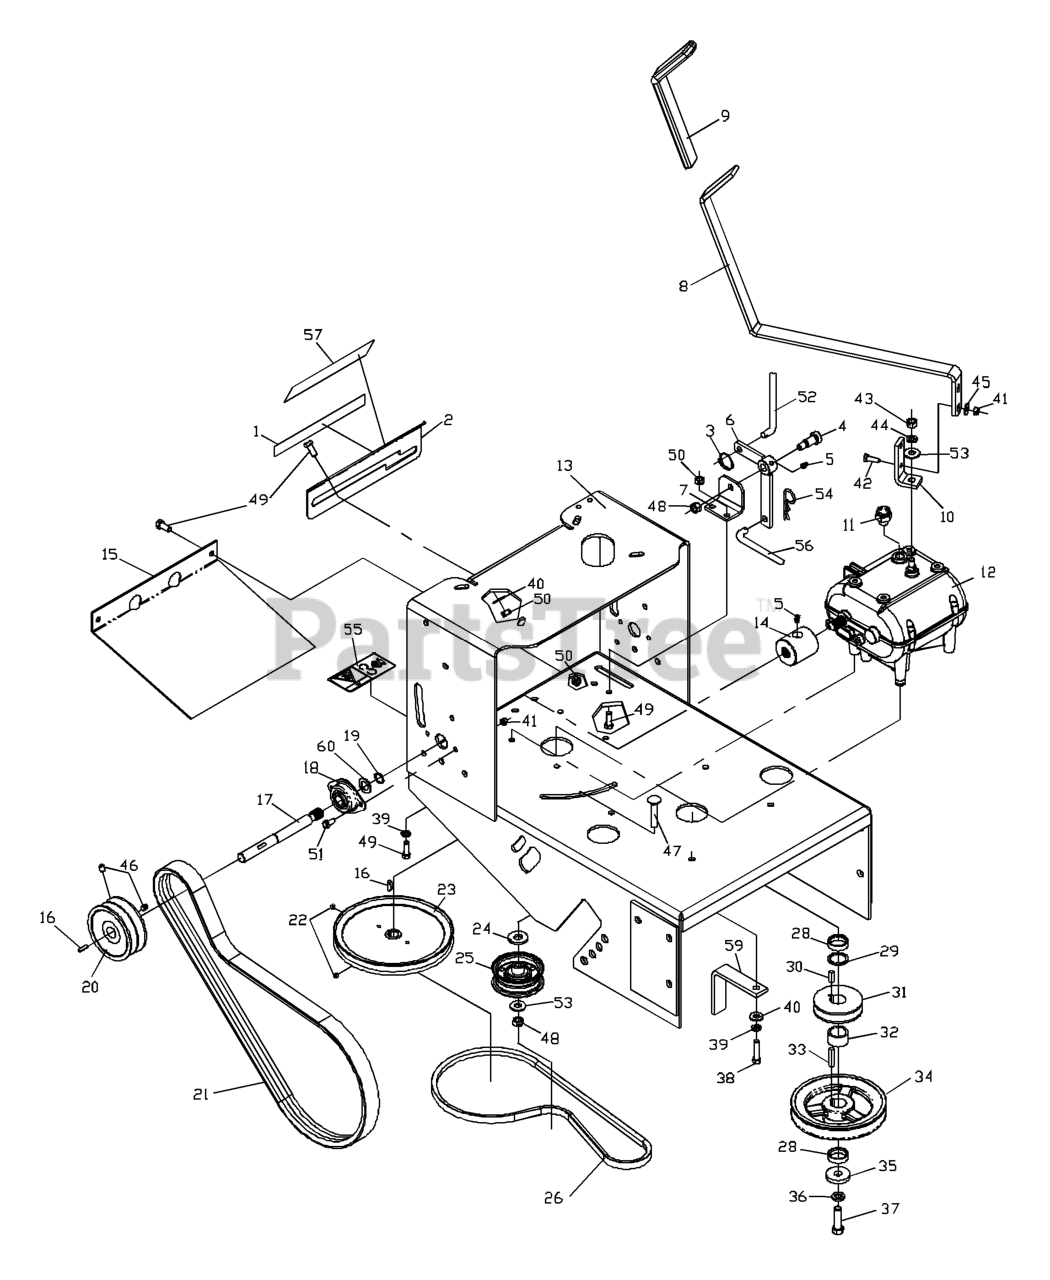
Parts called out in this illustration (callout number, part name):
1	DECAL, SHIFTER
2	SHIFTER PLATE
4	SB 12C X 34
5	ZERK
7	BRACKET-BELLCRANK-BLACK
8	SHIFTER ARM
9	SHIFTER GRIP
10	SHIFTER BRACKET
11	SWITCH, TRANS
12	TRANSMISSION WB
13	REAR DECK W/DECALS
15	LOWER BELT SHIELD
16	KEY, #9 WOODRUFF
17	DRIVE SHAFT
19	RETAINER RING
20	PULLEY, DRIVE (36 & 48)
21	BELT, DRIVE (36 & 48)
22	SETSCREW, 1/4-20 NYLOC
23	PULLEY, INPUT
24	WASHER 1/2 FLAT
25	IDLER PULLEY
26	BELT, TRANSMISSION
27	BELT GUIDE
29	BUSHING, 10GA MACHINERY
30	SQUARE KEY - 1/4 X .5
33	KEY 1/4 SQ X 1 1/8
34	PULLEY, ENGINE
35	SPINDLE WASHER
36	WASHER 7/16 LOCK
37	HCS 7/16F X 1 1/2
38	HEX SCREW 5/16 X 1.75
39	WASHER.LOCK.HVY.HLCL.SPR.5/16
40	WASHER 5/16 FLAT
41	NUT 1/4C CENTER LOCK
42	HCS 1/4C X 1
44	SLW 3/8 STD
45	WASHER 1/4 FLAT
46	SET SCREW 5/16 NYLOC
47	RHSNB 3/8C X 2
48	NUT 3/8C CENTERBLOCK
49	HCS 5/16C X 3/4
50	NUT 5/16C CENTERLOCK
51	HCS 1/4C X 5/8
53	WASHER 3/8 FLAT
54	HAIRPIN #4
55	DECAL, BELT DRIVE
56	BLADE ROD 48"
56	BLADE ROD 36"
57	DECAL, CLUTCH
58	BUSHING
59	BELT GUIDE - LONG
60	BELT GUIDE, SHORT
